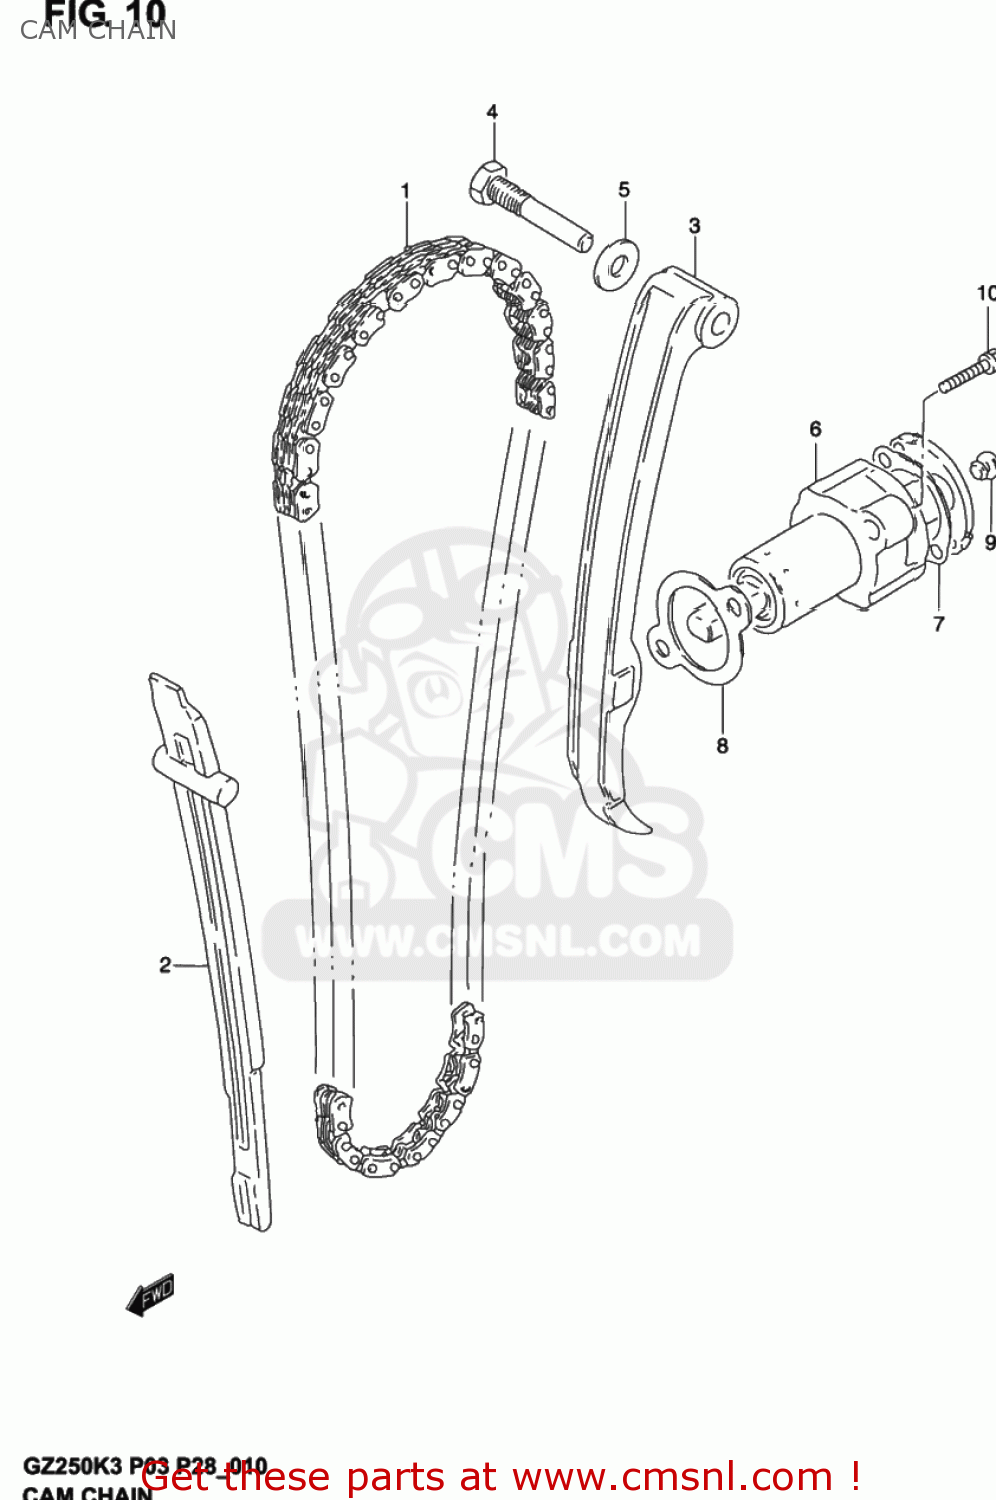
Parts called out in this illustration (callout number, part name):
1	CHAIN,CAMSHAFT DRIVE
2	GUIDE,CAM CHAIN
3	TENSIONER,CAM CHAIN
4	BOLT,CAM CHAIN TENSIONER
5	GASKET 8.2X14X1 (NAS)
6	ADJUSTER ASSY,TENSIONER
7	GASKET,ADJUSTER CAP (NAS)
8	GASKET,TENSIONER ADJUSTER (NAS)
9	PLUG,ADJUSTER
10	BOLT
